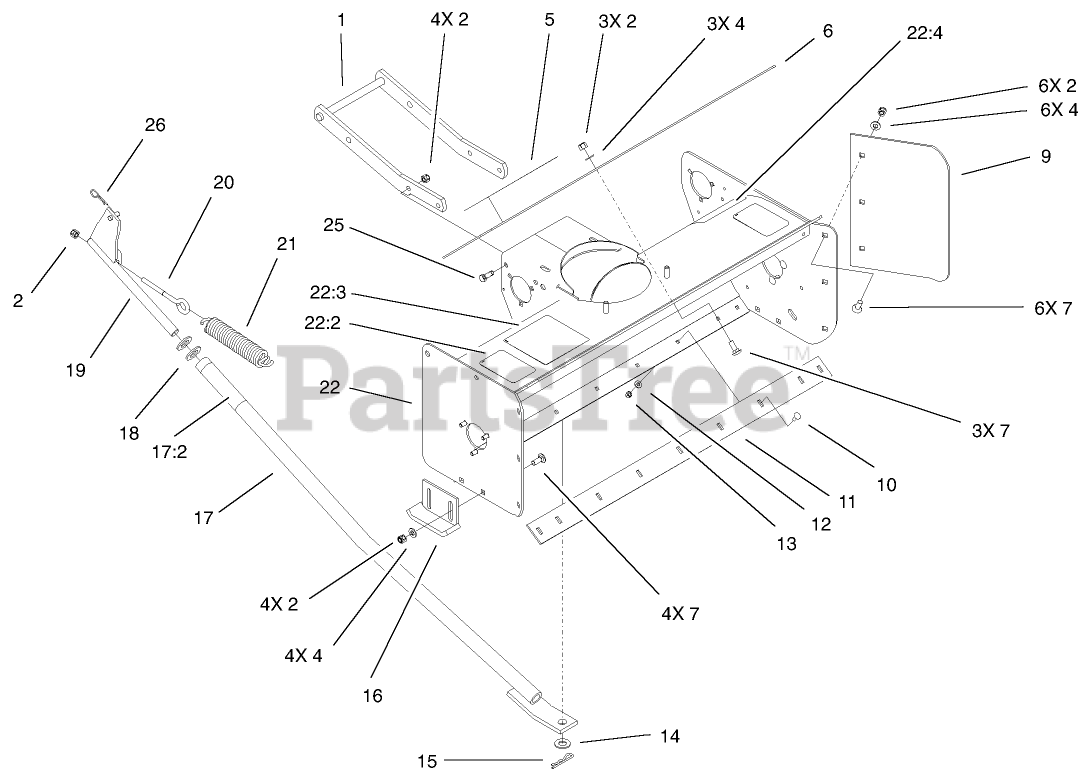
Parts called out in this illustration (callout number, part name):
1	FRAME-MOUNTING
2	NUT-LOCK, NI
4	WASHER-FLAT
6	PLATE-EXTENSION
7	BOLT-CARR
9	PLATE-EXTENSION, RH
12	WASHER-FLAT
13	NUT-LOCK, NI
14	WASHER-FLAT
15	PIN-COTTER, HAIR
17	LIFT TUBE W/DECAL ASM
17:2	DECAL - WARNING
18	WASHER-FLAT
20	EYEBOLT
21	SPRING
22	AUGER W/DECALS ASM
22:2	DECAL-DANGER
22:3	DECAL-WARNING
22:4	DECAL - WARNING
25	SCREW-HH
26	PIN-HAIR
